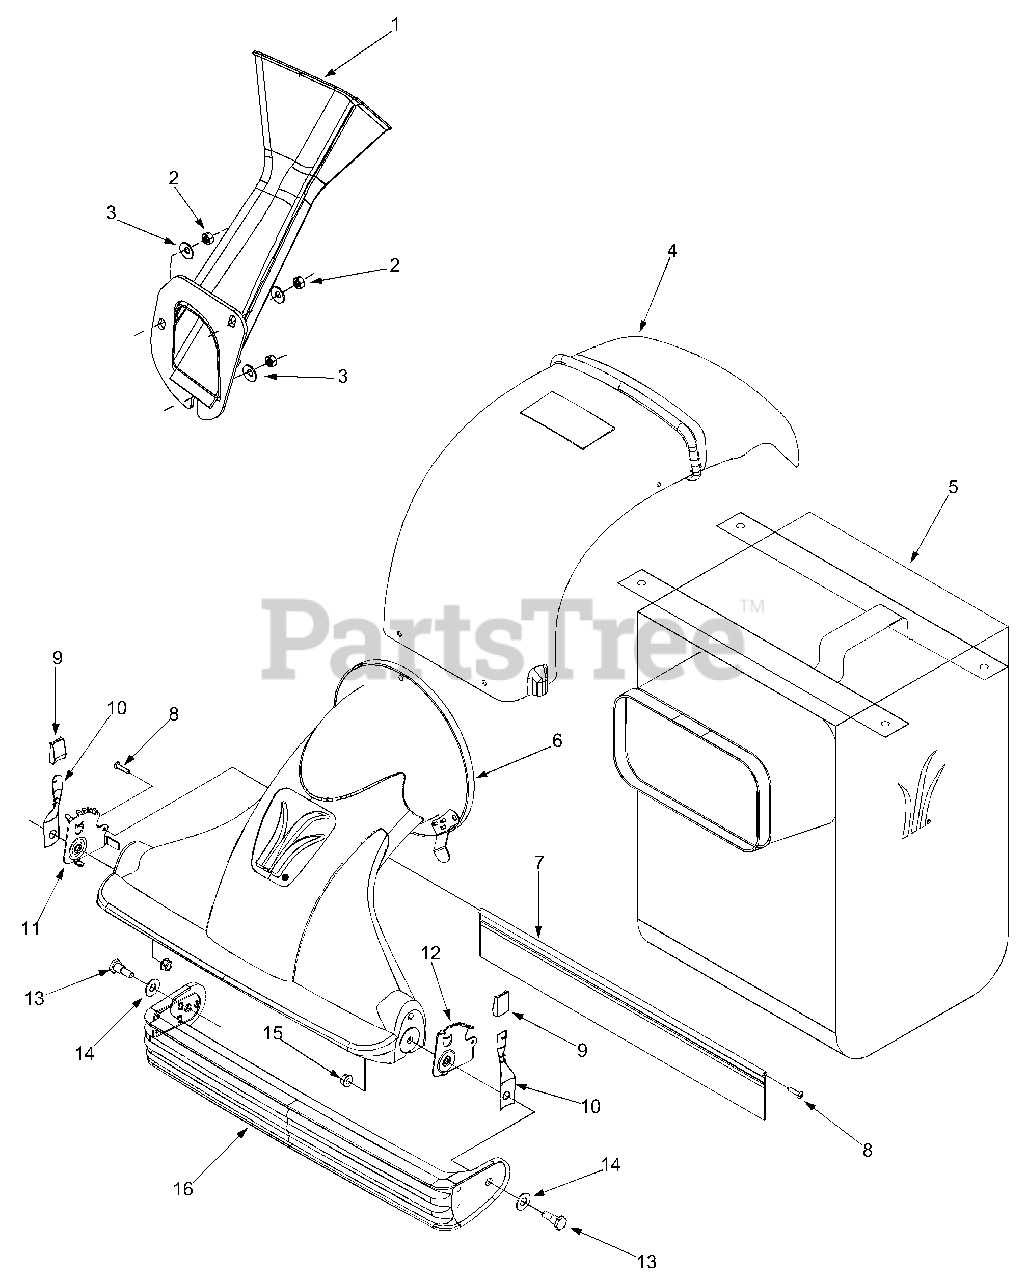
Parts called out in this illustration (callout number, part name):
2	Hex Nut 5/16-18
3	Bell Washer .340 ID x .872 OD
4	Discharge Chute
5	Bag
6	Nozzle Assembly
7	Nozzle Flap
8	Screw
9	Height Adjustment Knob
10	Spring Lever
13	Shoulder Screw
14	Flat Washer .510 x 1.12 x .060
15	Hex Flange Lock Nut 3/8-16
16	Door Assembly
